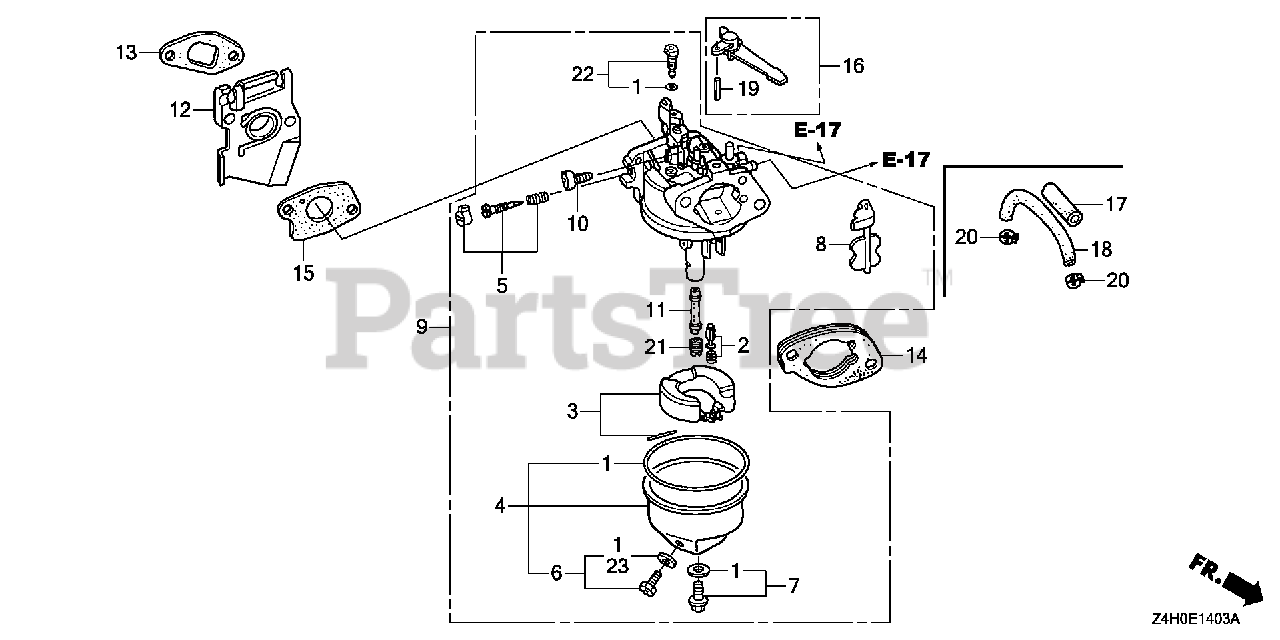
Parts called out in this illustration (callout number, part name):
1	GASKET SET (CARBURETOR NO.)
2	VALVE SET, FLOAT (CARBURETOR NO.) (SEAT NOT INCLUDED)
3	FLOAT SET
4	CHAMBER, FLOAT
5	SCREW SET (Honda Code 4219879). (CARBURETOR NO.)
6	SCREW SET, DRAIN
7	SCREW SET (CARBURETOR NO.)
8	CHOKE SET
9	CARBURETOR ASSY. (BE62L A)
9	CARBURETOR ASSY. (BE62J A)
10	SCREW, THROTTLE STOP
11	NOZZLE, MAIN
12	INSULATOR, CARBURETOR
13	GASKET, INSULATOR
14	SPACER, CARBURETOR
15	GASKET, CARBURETOR
16	LEVER, CHOKE (STD)
17	RUBBER, SUPPORTER (107MM)
18	TUBE, FUEL (4.2X400)
18	TUBE, FUEL (4.5X400) (FKM)
19	PIN, SPRING (2X12)
20	CLIP, TUBE (D8)
21	JET, MAIN (#58) Use from Engine SN BE30B E.
21	JET, MAIN (#60)
21	JET, MAIN (#62)
22	JET SET, PILOT (#35)
